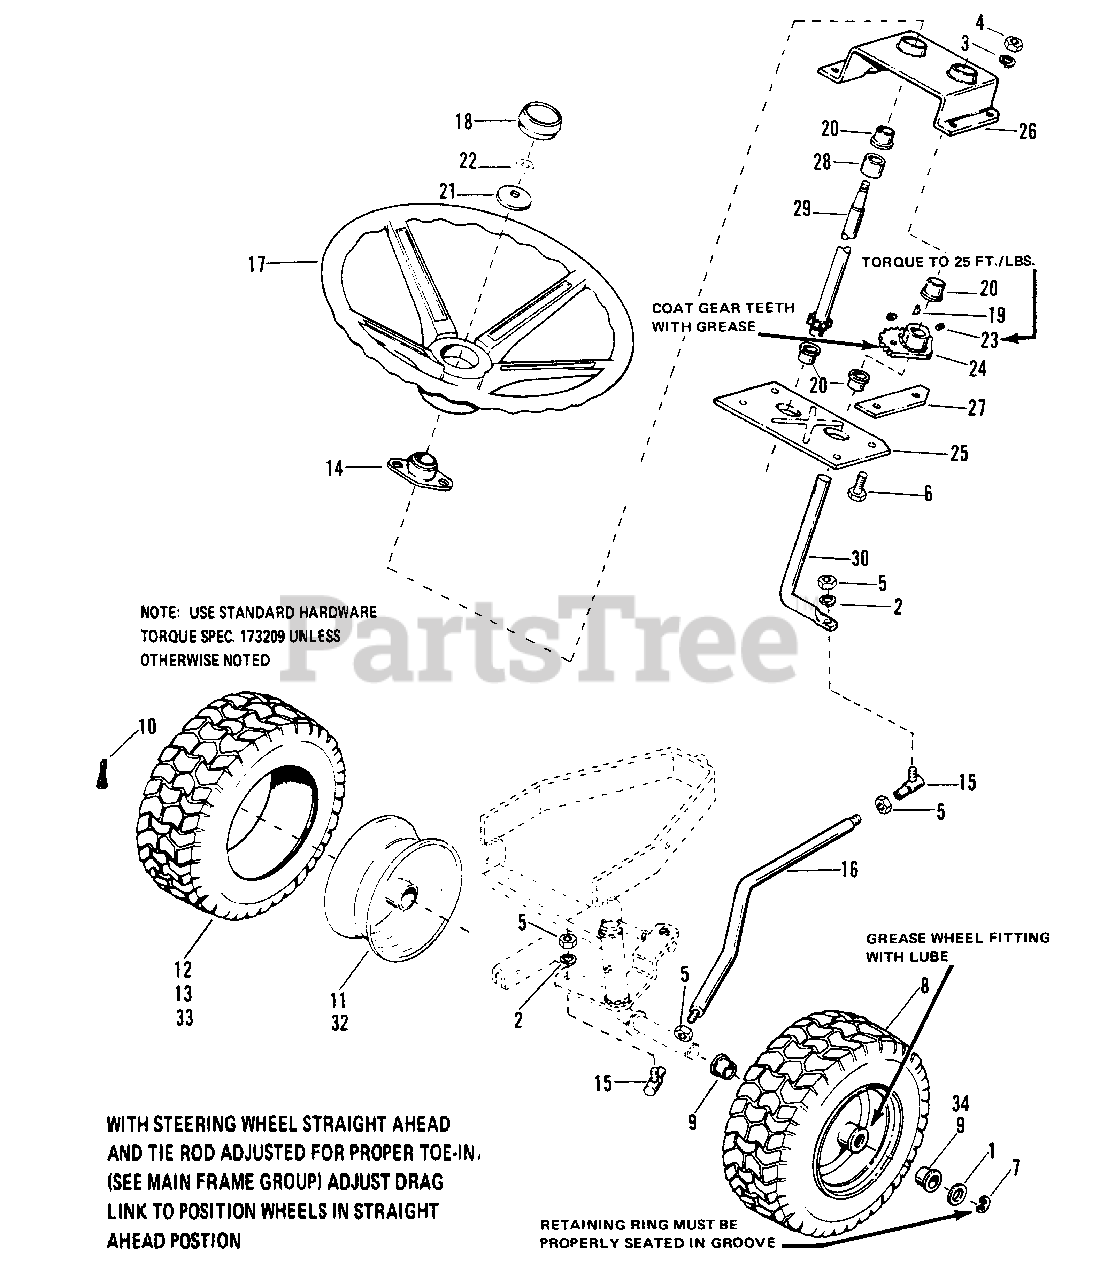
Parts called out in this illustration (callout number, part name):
2	LOCKWASHER, Spring, 3/8
4	LOCKNUT, Whiz, 5/16-18
5	NUT, Hex Jam, 3/8-24
6	CAPSCREW, Hex Hd., 5/16-18 x 1
7	RING, Retaining
8	WHEEL & TIRE ASSY, 15 x 6.00-6
9	BEARING, Relief
10	VALVE, Stem & Cap
11	WHEEL & BUSHING ASSY, 15-6
12	TIRE, 15 x 6.00-6, Carlisle
13	GOODYEAR TIRE, 15 x 6.00-6
15	BALL JOINT ASSY
16	DRAG LINK ASSY
17	WHEEL, Steering
18	CAP, Steering Wheel
21	WASHER, Compression
22	LOCKNUT, Hex Full, 5/16-18
23	SCREW, Set, Sq.Hd. Cup Pt., 5/16-18 x 5/8
24	GEAR, Steering
25	BASE PLATE, Steering
26	TOP PLATE, Steering
27	SPACER, Stop
29	SHAFT ASSY, Steering
30	ROD, Steering
